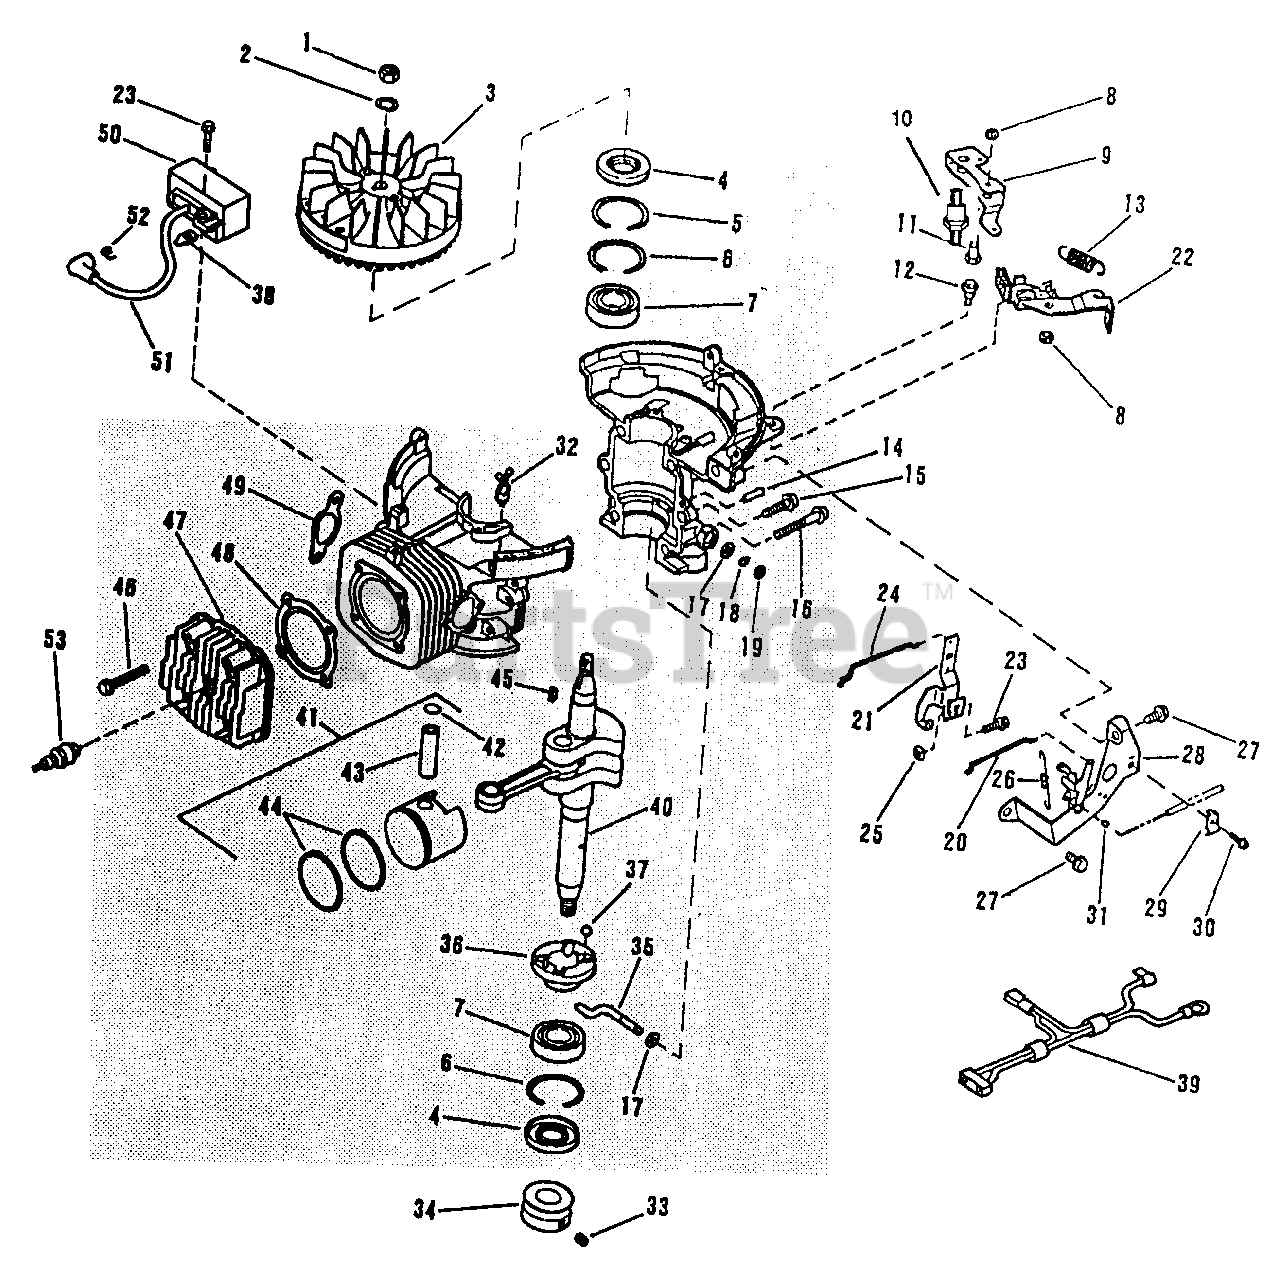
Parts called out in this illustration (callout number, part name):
1	Nut-Flywheel
2	Lockwasher
3	Flywheel
4	Oil Seal-Crankshaft
5	Retaining Ring
6	Retaining Ring
7	Bearing-Crankshaft
9	Brake Actuator Lever
10	Shoulder Stud-Actuator Lever
11	Shoulder Bolt
12	Shoulder Bolt-Brake Arm
13	Brake Spring
14	Taper Pin
15	Screw
16	Screw
17	Washer-Governor Shaft
18	Retainer Ring-Governor Shaft
19	Oil Seal-Governor Shaft
20	Choke Rod
21	Governor Control Lever
22	Brake and Switch Kit
23	Screw
24	Throttle Rod
25	Nut
26	Governor Spring
27	Screw
28	Governor Bracket Assembly
29	Clamp-Throttle Cable to Bracket
30	Screw
31	Throttle Control Wire Retainer
32	Wire Tie
33	Set Screw
34	Engine Pulley
35	Governor Shaft
36	Governor Ramp
37	Ball-Governor
38	Terminal-C.D. Ignition Module
39	Wire Harness
40	Crankshaft and Connecting Rod
41	Piston and Ring Assy. (Standard)
42	Retaining Ring
43	Wrist Pin
44	Ring Set (Standard)
45	Key-Crankshaft
46	Screw-Cylinder Head to Block
47	Cylinder Head
48	Head Gasket
49	Exhaust Gasket
50	C.D. Ignition Module
51	High Tension Lead and Cover
52	Spring Terminal
53	Spark Plug
